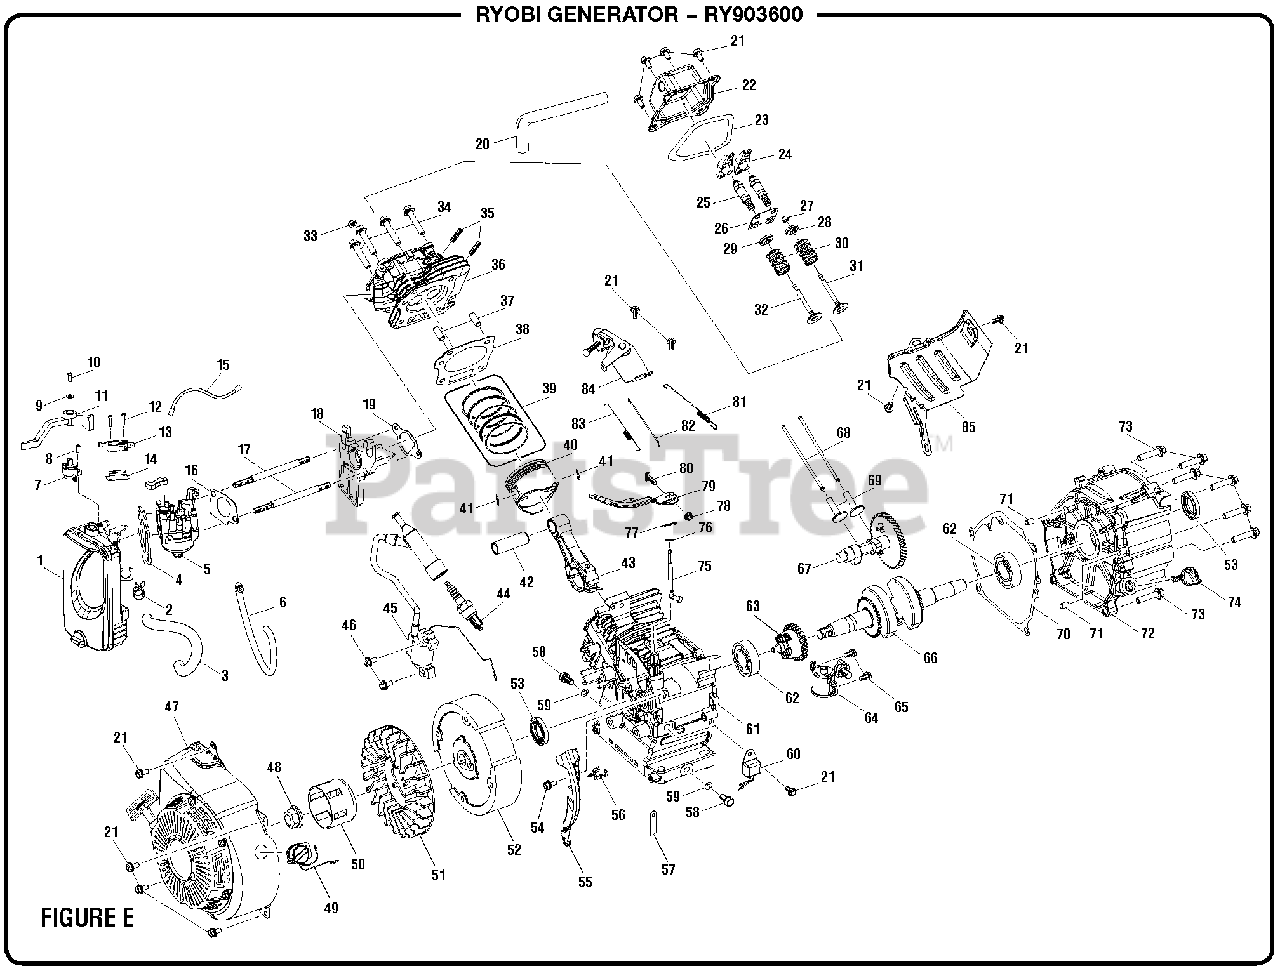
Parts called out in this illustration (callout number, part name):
1	Air Cleaner Assembly
2	Fuel Line Clip
4	Air Cleaner Gasket
5	Carburetor Assembly
6	Fuel Line
7	Fuel Valve
8	Screw (M4 x 12 mm)
10	Screw (M6 x 10 mm)
11	Choke Lever
13	Switch Assembly
14	Engine Switch Bracket
15	Flameout Wire
16	Carburetor Gasket
17	Threaded Stud
18	Carburetor Insulator
19	Intake Gasket
20	Breather Tube
21	Bolt (M6 x 12 mm)
22	Cylinder Head Cover
23	Cylinder Head Cover Gasket
24	Rocker Assembly
25	Rocker Arm Assembly (Set of Two)
26	Guide Plate (Push Rod)
28	Valve Spring Seat (Exhaust)
29	Valve Spring Seat (Intake)
30	Valve Spring
31	Exhaust Valve
32	Intake Valve
33	Intake Valve Return
34	Bolt (M8 x 60 mm)
35	Threaded Stud
36	Cylinder Head
37	Dowel Pin
38	Cylinder Head Gasket
39	Piston Ring Set
41	Piston Clip
42	Piston Pin
43	Connecting Rod Assembly
44	Spark Plug
45	Ignition Coil Assembly
46	Bolt (M6 x 25 mm)
47	Recoil Starter Assembly
48	Hex Flange Nut (M14)
49	Switch Assembly
50	Starter Pulley
51	Recoil Starter Fan
52	Flywheel Assembly
53	Oil Seal
55	Wind Shield
57	Wiring Harness Clip
58	Bolt (Drain Plug)
59	Washer (Drain Plug)
60	Amplifier
61	Crankcase
62	Ball Bearing
63	Governor Assembly
64	Switch Assembly (Oil Level)
65	Bolt (M6 x 16 mm)
66	Crankshaft Assembly
67	Camshaft Assembly
69	Valve Lifter
70	Casecover Gasket
71	Dowel Pin (Case Cover)
72	Crankcase Cover Assembly
75	Governor Arm Shaft
76	Washer (Governor Arm Shaft)
78	Hex Flange Nut (M6)
79	Governor Arm
80	Bolt (Governor Arm)
81	Throttle Return Spring
82	Governor Rod
83	Governor Spring
84	Upper Shroud Assemlby
